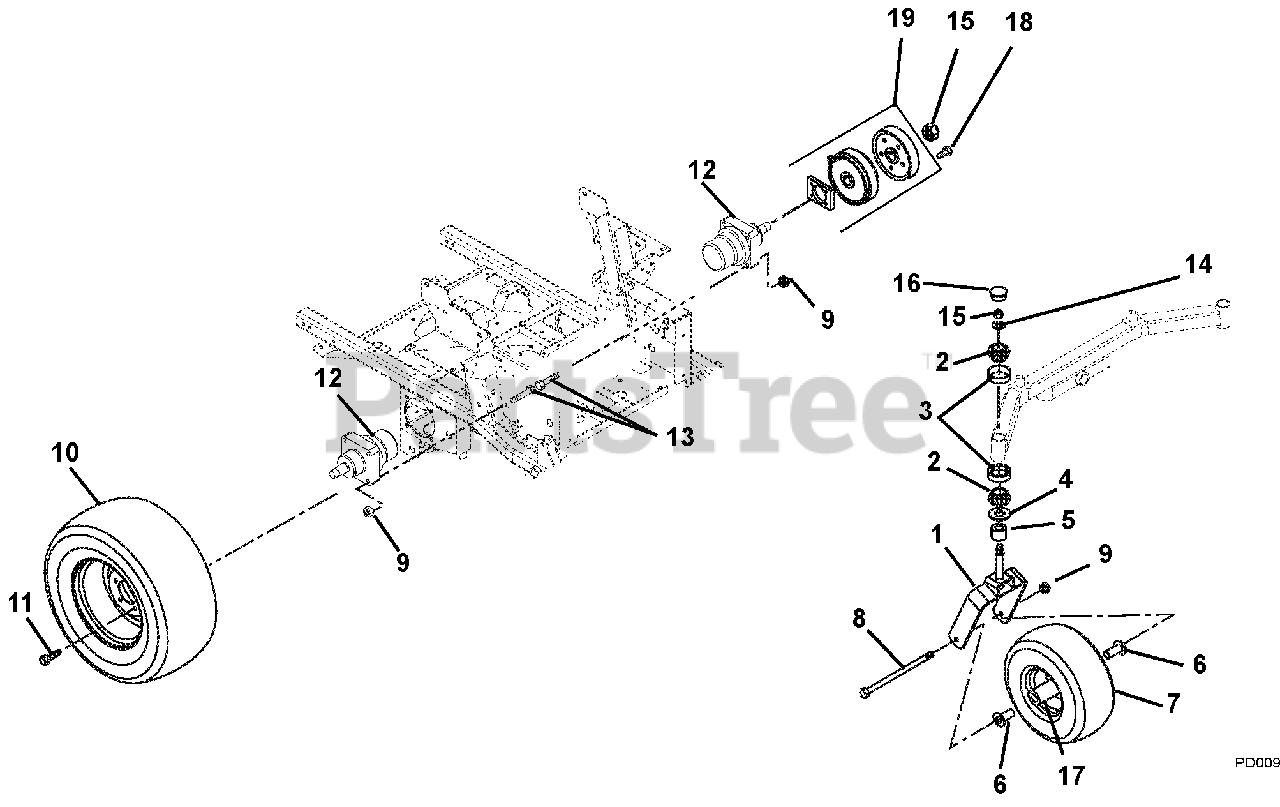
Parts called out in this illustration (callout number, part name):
2	Bearing, Cone with Grease
3	Bearing, Cup 1.98 x .420
4	Bearing Seal 1.5 x 2 x .18
5	Spacer, PM, 1.03 I.D. x 1.5 O.D. x .375
6	Spacer, Wheel
7	Wheel/Tire Assembly
8	Bolt, Hex .50-13 x 9.00 Grade 5
9	Nut, Locking Top Flange .50-13
10	Tire/Wheel Assembly 24 x 12-12 (992148, 149, 150, 151, 152, 153, 154, 155, 157, 159)
11	Bolt, Lug Grade 8 .50-20 UNF x 1.38 Long 60 Degree
12	Hydraulic Wheel Motor (992148, 149, 150, 151, 152, 153, 154, 155, 157, 159)
13	Bolt, Wheel Motor .50-13 x 2.75 (992148, 149, 150, 151, 152, 153, 154, 155, 157, 159)
14	Washer, Flat, Steel .812 x 1.50 x .135
15	Nut, Jam Center Lock .75-16
16	Cap, Dust
17	Bearing, 25mm I.D. x 52mm OD x 15mm
18	Bolt, Hex .31-18 x 1.5 Grade 5
19	Kit, Parking Brake Service
